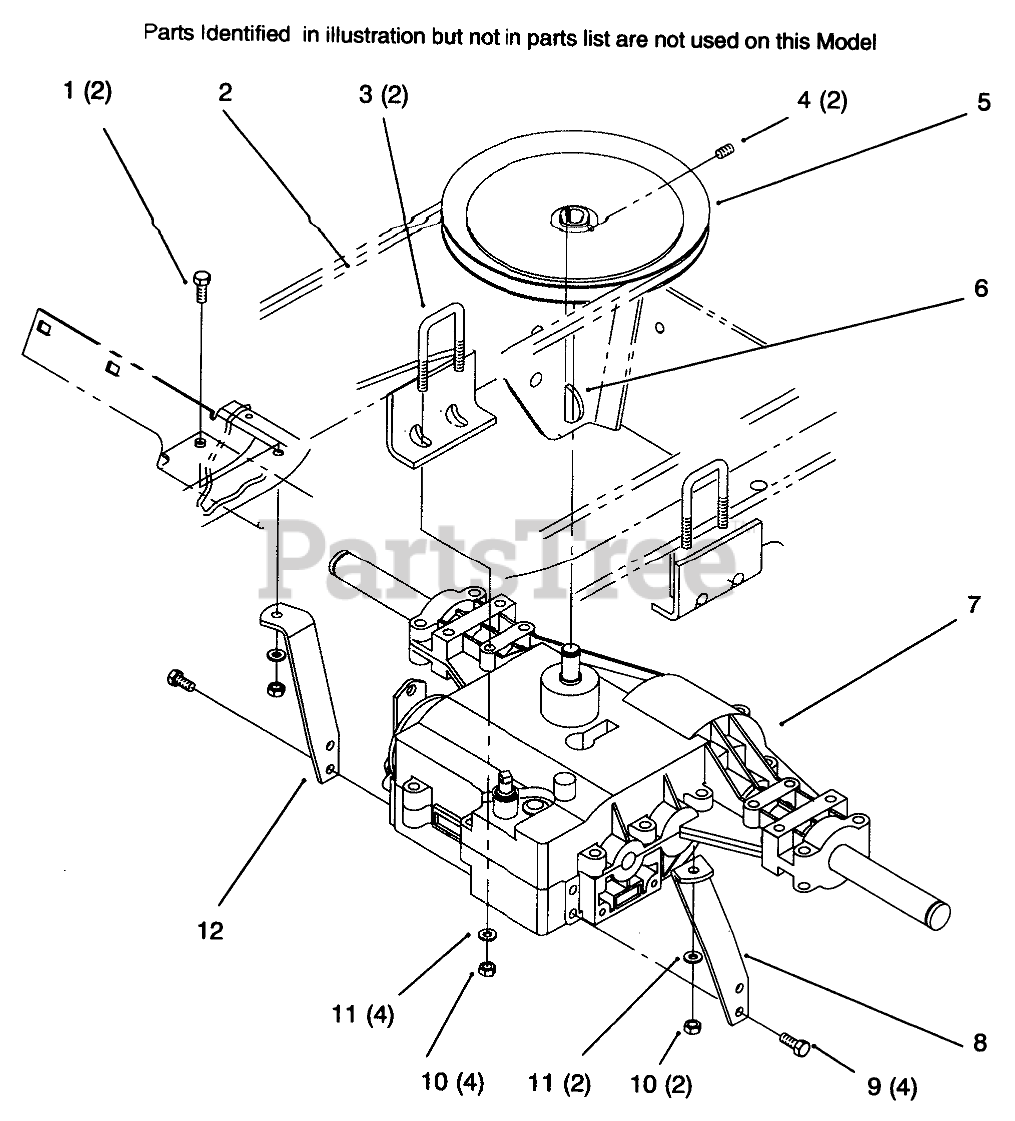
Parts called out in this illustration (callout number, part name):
1	SCREW-HH
2	Belt-Gear
3	U-BOLT
4	SCREW-SQ HD SET
5	PULLEY-TRANS (GEAR)
6	KEY-HI-PRO
7	TRANSAXLE 820-024
8	STRAP - LH TORQUE
9	SCREW-HWHTF
10	NUT-LOCK, NI
11	WASHER-PLAIN
12	STRAP - RH TORQUE
